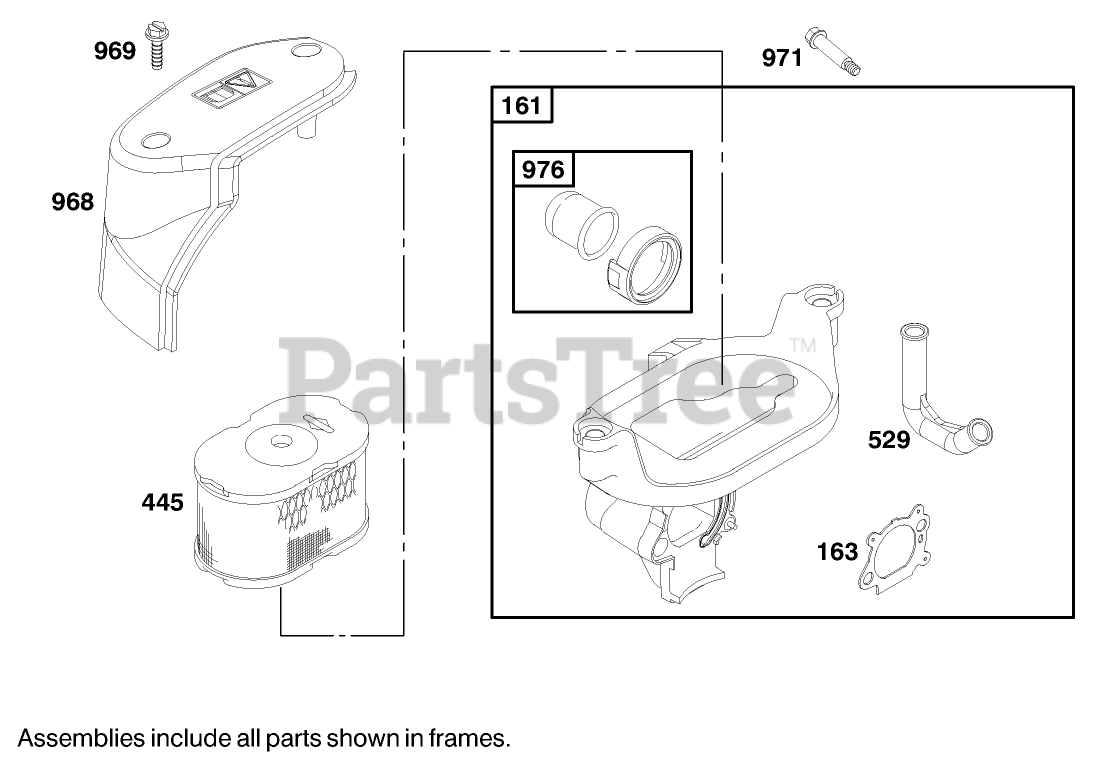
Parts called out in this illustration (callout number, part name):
161	Base-A/C Primer
163	Gasket-Cleaner, Air
445	Air Filter
529	Tube-Breather
968	Air Cleaner Cover
969	Screw
971	Screw-Shoulder
976	CarburetorPrimer
